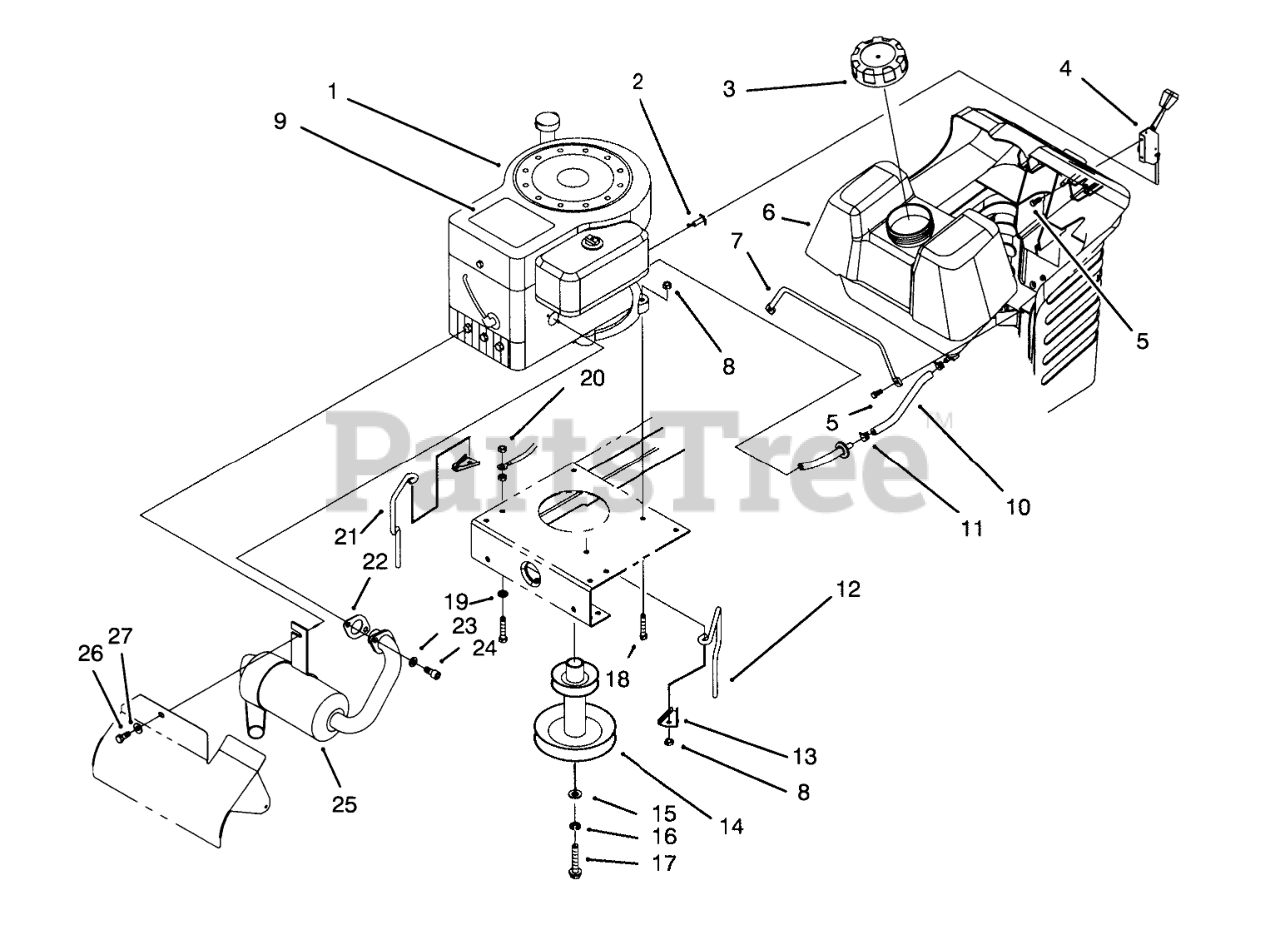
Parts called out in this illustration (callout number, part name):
1	Engine-13 H.P.
2	THROTTLE CABLE ASM
3	GAS CAP ASM
4	THROTTLE CONTROL ASM
5	SCREW-SPECIAL
6	GAS TANK ASM
7	GAS TANK ROD
8	NUT-LOCK, NI
9	DECAL - ENGINE
10	HOSE-FUEL
11	CLAMP-HOSE
12	LH BELT GUIDE
13	ANCHOR-GUIDE, BELT
14	ENGINE PULLEY
15	WASHER-FLAT
16	WASHER-LOCK
17	SCREW-HH
18	SCREW-HH
19	WASHER-LOCK
20	NUT-KEPS
21	RH BELT GUIDE
22	GASKET-EXHAUST
23	WASHER-LOCK
24	SCREW-HSH
25	MUFFLER
26	SCREW-HH
27	WASHER-LOCK
